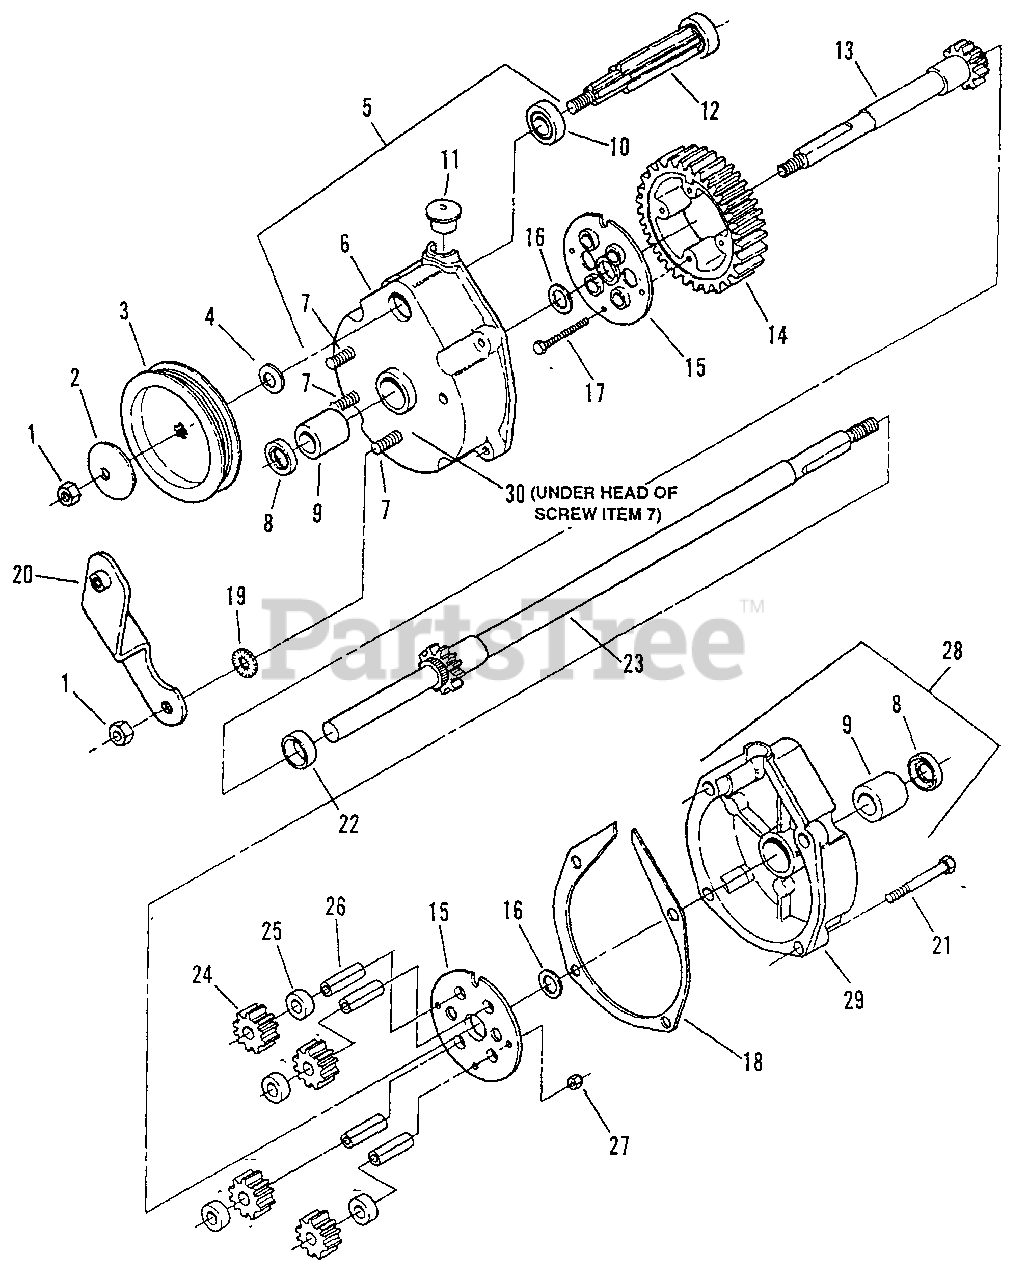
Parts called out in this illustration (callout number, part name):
1	NUT, 5/16-24 Hex Lock, Grade C
2	WASHER, Spring
3	PULLEY, Poly-Vee Belt
4	WASHER, Spring
5	ASSEMBLY, Housing Right
6	HOUSING, Right Side
7	SCREW, 5/16-24 x 1-1/8" Rib Neck, Grade 5
8	SEAL, 5/8 I.D.
9	BEARING, Differential
10	BEARING, Ball
11	PLUG, Housing
12	GEAR, Input
13	AXLE, Short
14	GEAR, Differential (46 Tooth)
15	PLATE
16	WASHER, Thrust
17	SCREW, #10-32 x 1-1/2" Hex Head Cap, Grade 5
18	GASKET, Housing
19	WASHER, 5/16 internal/External Tooth Lock
20	BRACKET, Differential
21	SCREW, 1/4-20 x 1-1/4" Self-Tapping
22	SPACER, Axle Gear
23	AXLE,Long
24	GEAR, Pinion (12 Tooth)
25	SPACER, Pinion Gear
26	SHAFT, Pinion
27	NUT, #10-32 Hex Nyloc
28	ASSEMBLY, Housing Left
29	HOUSING, Left Side
30	GASKET, 5/8 O.D.
